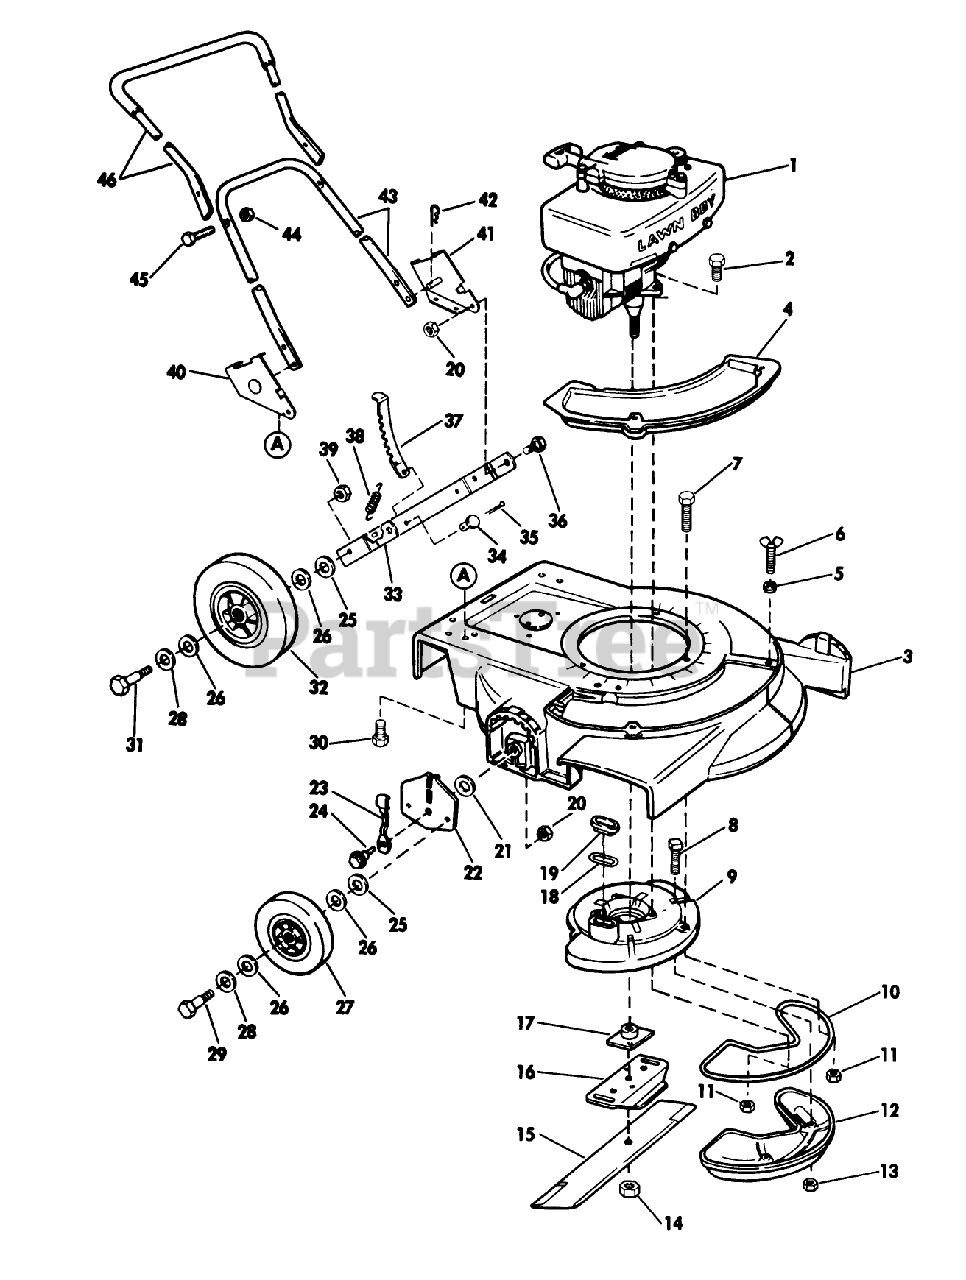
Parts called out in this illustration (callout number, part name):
1	Engine-Model C-18
13	LOCKNUT E
14	NUT-BLADE
17	PLATE AND COLLAR ASM
18	GASKET S
25	WASHER WROUGHT
29	BOLT WHEEL
36	BOLT-SHOULDER
38	SPRING N.A.S
39	LOCKNUT
42	HAIR PIN
